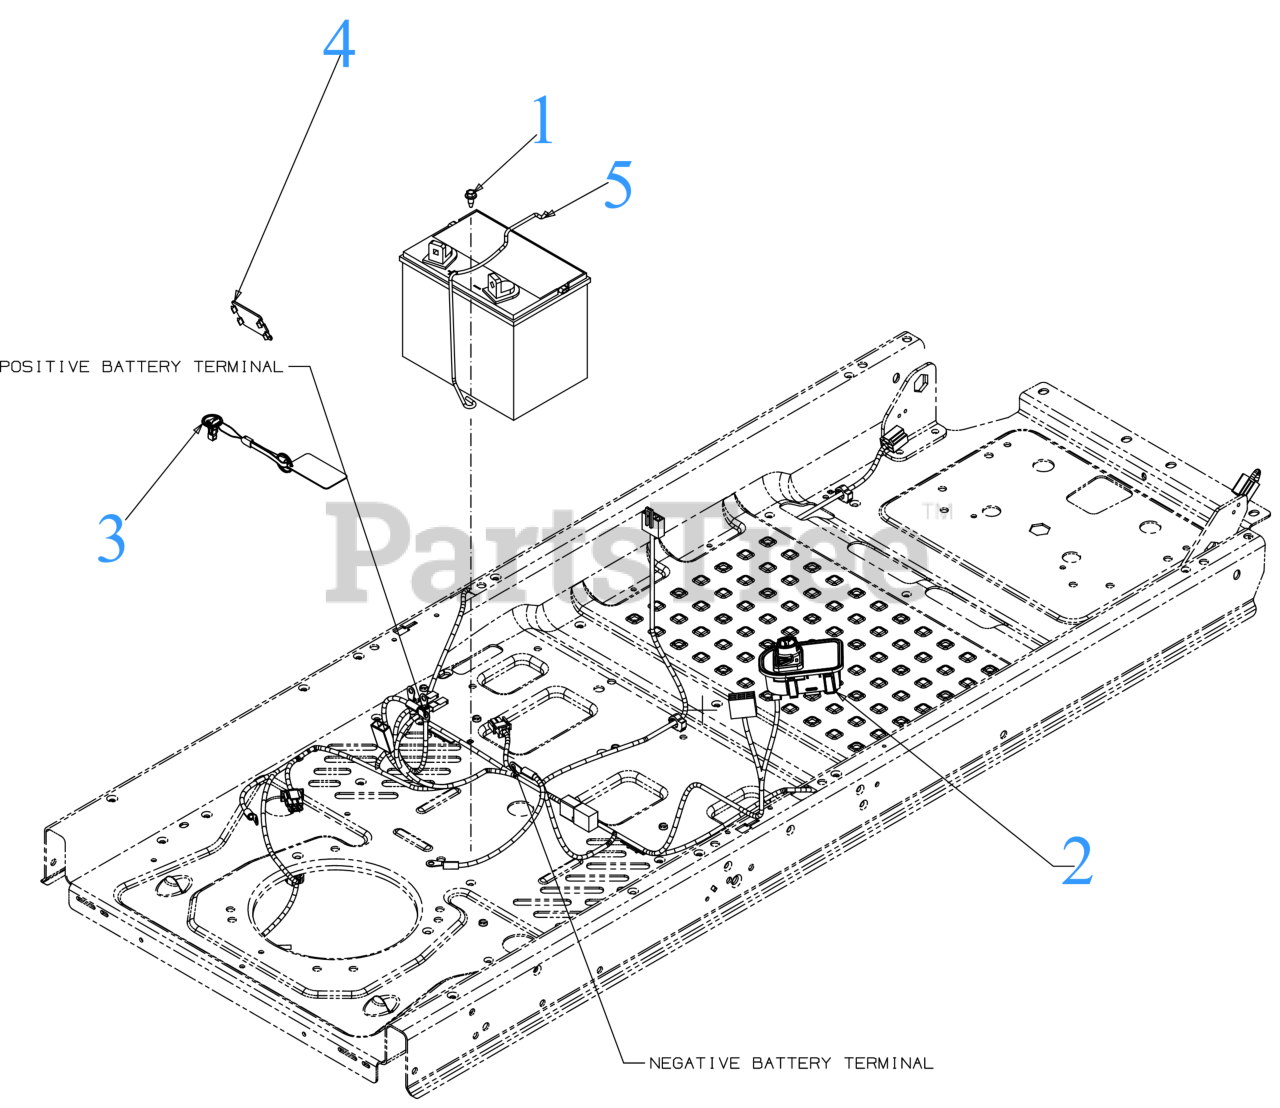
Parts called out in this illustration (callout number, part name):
1	SCREW 1/4-20X.625
2	MODULE (PBS/HRMTR/SVC MNDR)
3	PBS KEY
3	Cub Cadet PUSH BUTTON KEY
4	AMMETER DASH PLUG
